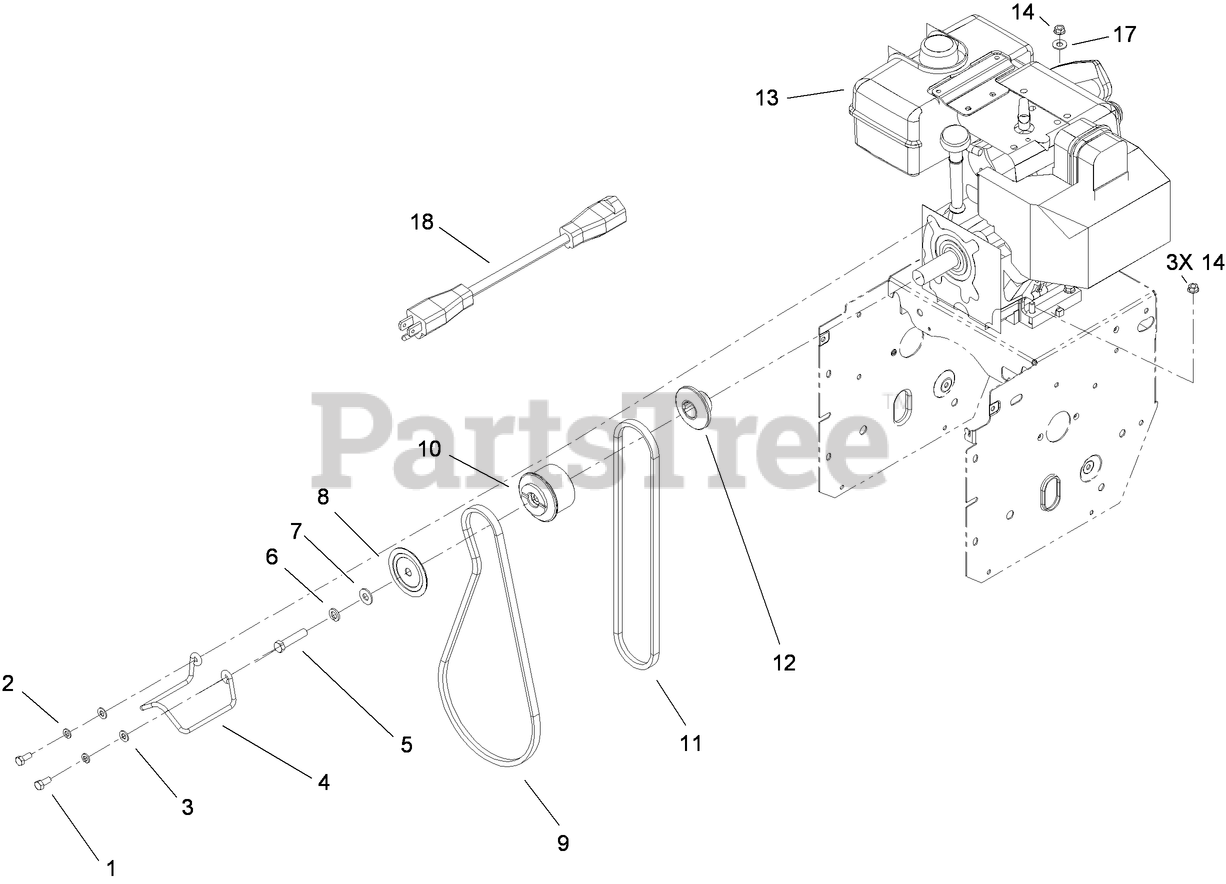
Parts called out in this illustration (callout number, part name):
1	SCREW-HH
2	WASHER-LOCK
3	WASHER-PLAIN
5	SCREW-HH
6	WASHER-LOCK
7	WASHER-FLAT
8	SHEAVE-HALF, IMPELLER
9	BELT-V
10	PULLEY-ENGINE, CENTER
11	V BELT-TRACTION
12	SHEAVE-HALF, TRACTION
13	Loose Parts Package
14	NUT-HF
17	WASHER-FLAT
18	CORD-EXTENSION (only on: 38078)
